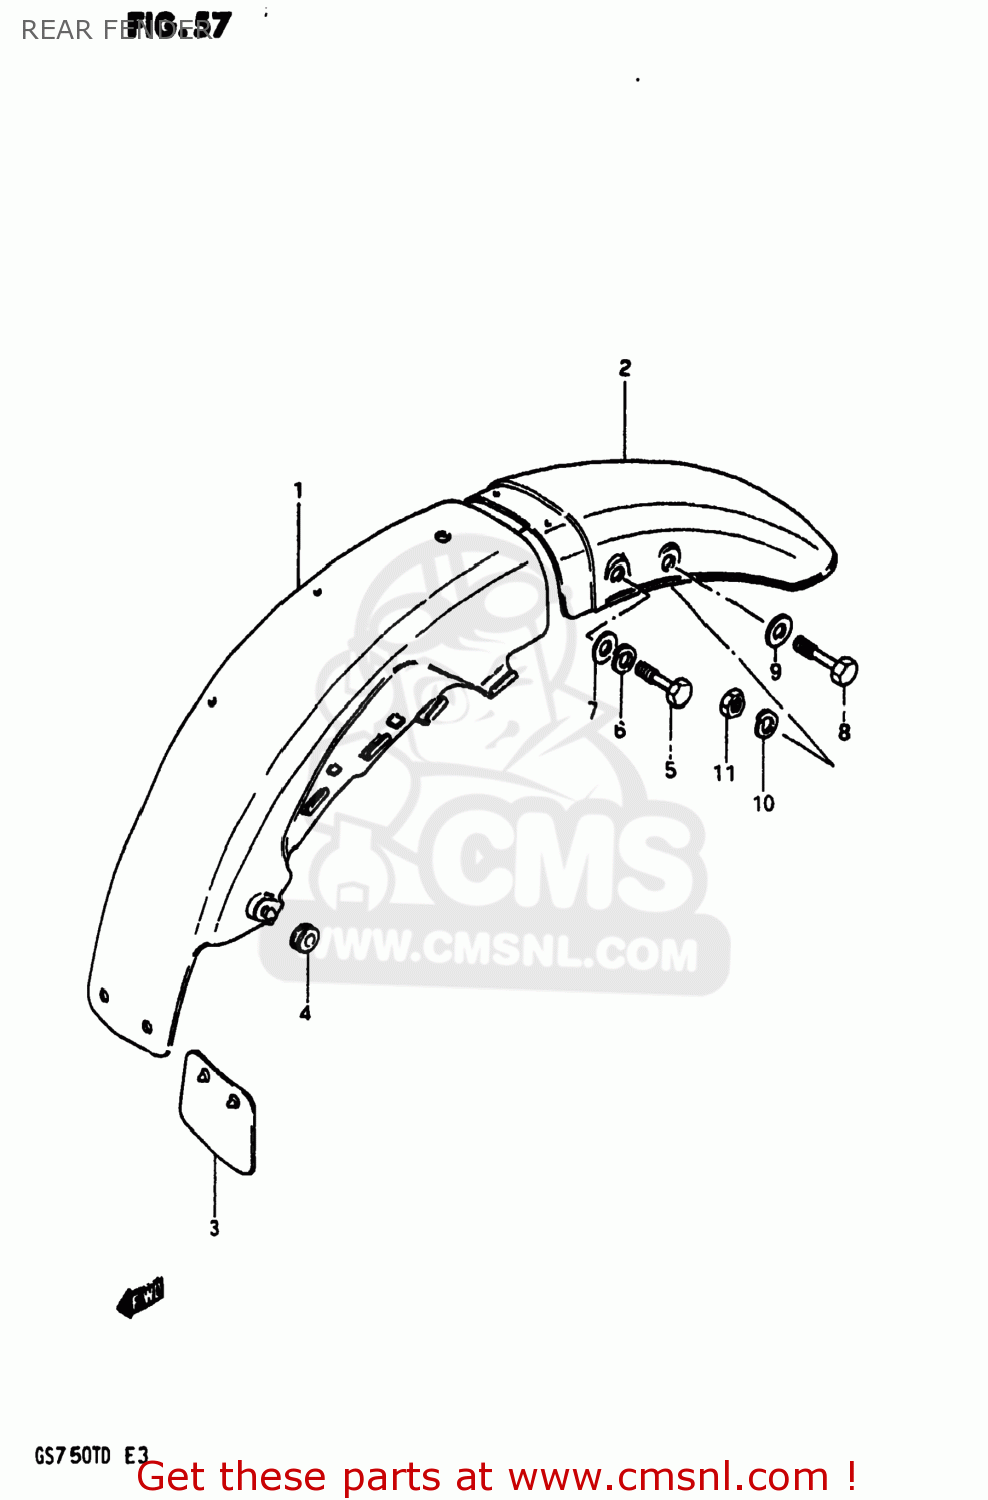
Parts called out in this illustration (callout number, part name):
1	FENDER,REAR
2	FENDER,REAR
3	GUIDE,RR FENDER MUD
4	CUSHION
5	BOLT, UPPER
6	LOCK WASHER
7	WASHER(6.5X16X1.2)
8	BOLT
9	WASHER
10	LOCK WASHER
11	NUT 8MM
